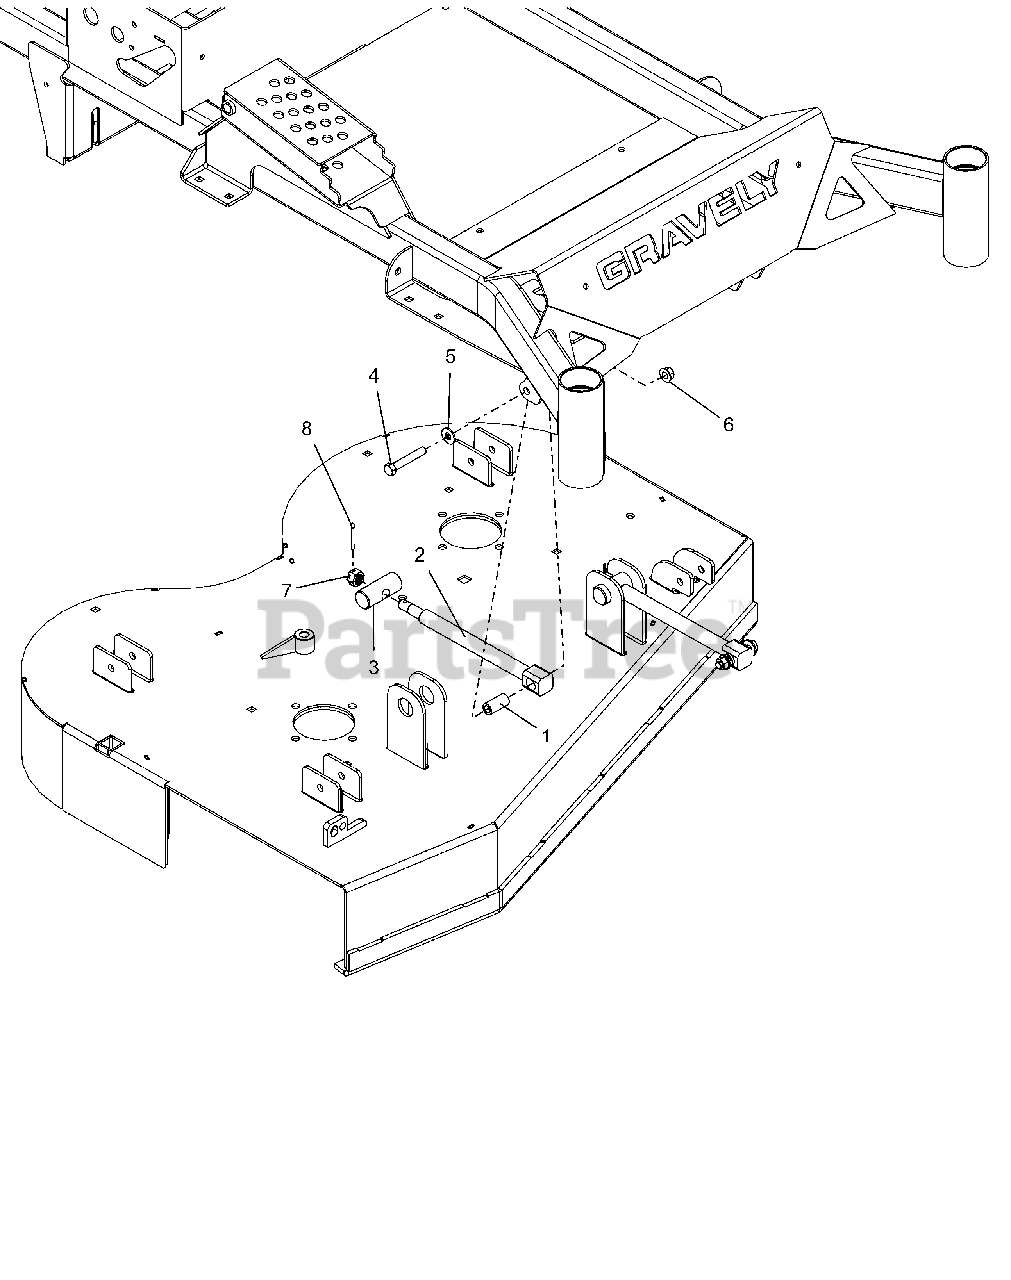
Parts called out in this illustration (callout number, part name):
1	SPACER, DECK LEVELING
2	DRAG,LINK-HD
3	PIN, DECK LIFT
4	BLT,HEX .38-16X2.25 G5 ZCC
5	WSHR,FLT .375X.875X.083 ZCC
6	NUT-LK-CTR-FLG .375-16 GF ZCC
7	NUT-SL .50-13
8	PIN,CTR.12X1.25EXTPRSQCT ZC120
